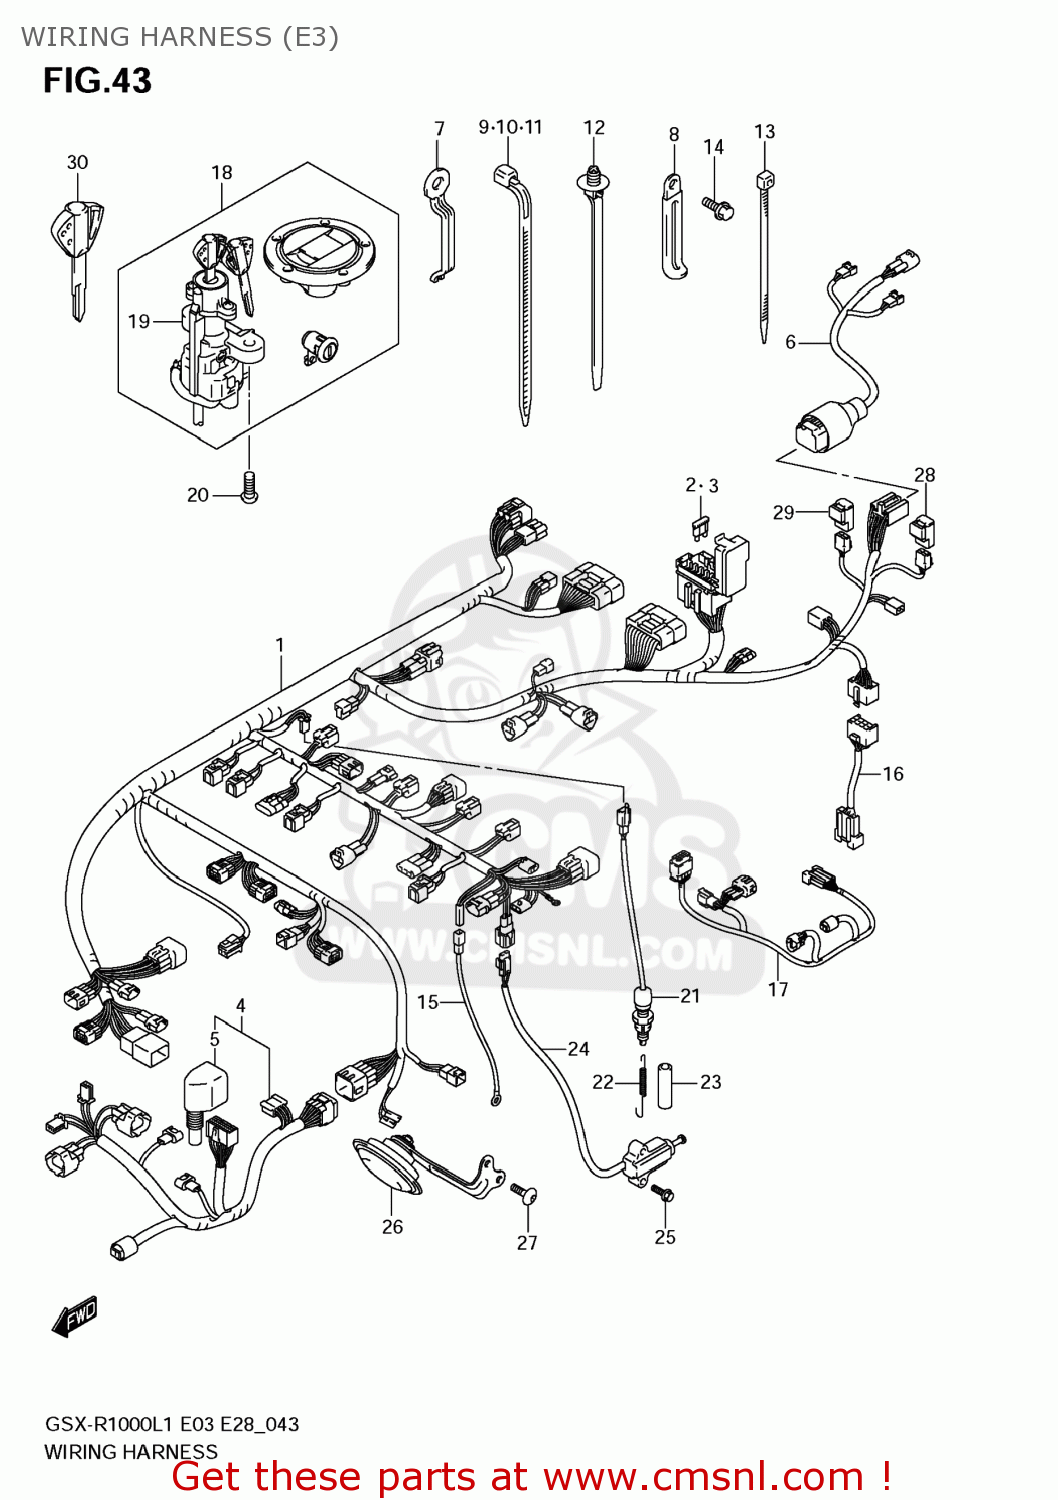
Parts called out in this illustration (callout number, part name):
1	HARNESS,WIRING NO.1
2	FUSE(10A)
3	FUSE(15A)
4	HARNESS,WIRING NO.2
5	COVER,CONNECTOR
6	WIRE,RR COMB
7	CLAMP
8	CLAMP(L:45)
9	CLAMP(L:125)
10	CLAMP(L:165)
11	CLAMP(L:190)
12	CLAMP(L:154)
13	CLAMP(L:145)
14	BOLT
15	WIRE,OIL PRESSURE SWITCH LEAD
16	WIRE,RELAY LEAD
17	WIRE,ISC LEAD
18	LOCK SET
19	LOCK ASSY,STEERING
20	BOLT(8X20)
21	SWITCH ASSY,STOP LAMP
22	SPRING
23	HOSE(5X8.2X600)
24	SWITCH ASSY,SIDE STAND
25	BOLT
26	HORN ASSY
27	SCREW(6X16)
28	RELAY ASSY
29	RELAY ASSY
30	KEY,BLANK(IMMOBII)
